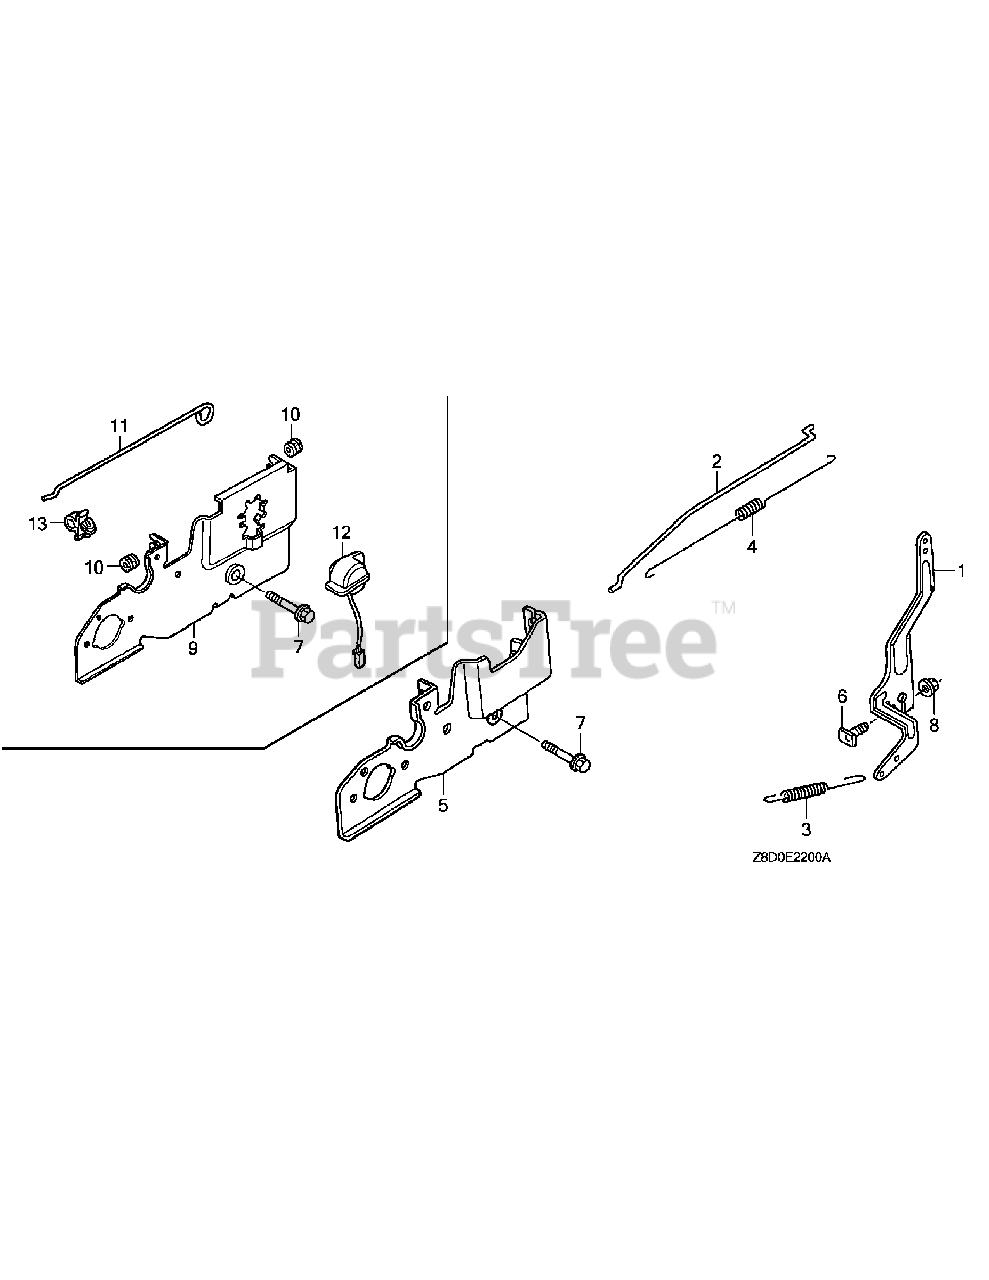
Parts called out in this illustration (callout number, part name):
1	Governor Arm
2	Governor Rod
3	Governor Spring
4	Throttle Return Spring
5	Control Base Complete
6	Governor Arm Bolt
7	Flange Bolt, 6 x 45 (CT200)
8	Flange Nut, 6mm
9	Not used in this application
10	Not used in this application
11	Not used in this application
12	Not used in this application
13	Not used in this application
